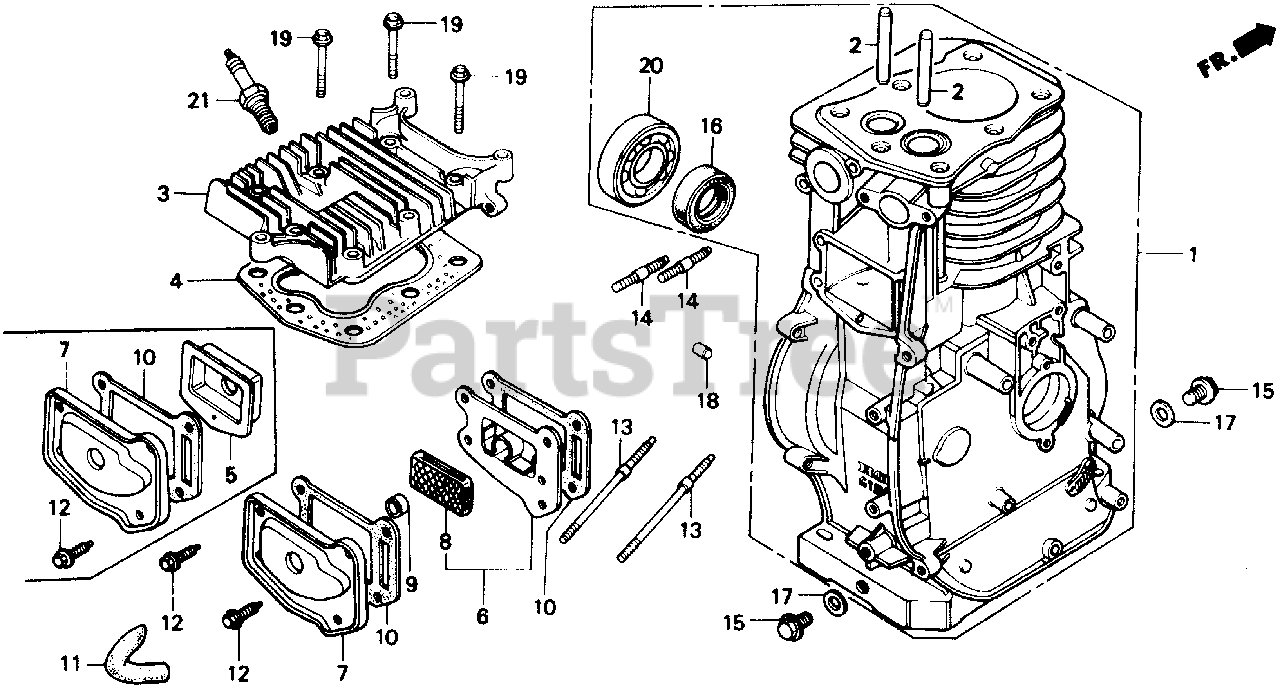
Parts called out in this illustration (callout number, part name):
1	CYLINDER ASSY.
2	GUIDE, VALVE (OS)
3	CYLINDER HEAD
4	GASKET, CYLINDER HEAD
5	CASE, BREATHER
6	CASE, BREATHER
7	COVER, TAPPET ROOM
8	FILTER, BREATHER
9	SEAL, BREATHER
10	GASKET, TAPPET COVER
11	TUBE, BREATHER
12	BOLT, FLANGE (6X12) (CT200)
13	BOLT, STUD (6X89)
14	BOLT, STUD (8X35)
15	BOLT, DRAIN PLUG
16	OIL SEAL (25X41X6)
17	WASHER, DRAIN PLUG (12MM)
18	PIN A, DOWEL (8X14)
19	BOLT, FLANGE (8X45)
20	BEARING, RADIAL BALL (6205)
21	SPARK PLUG (BR-4HS) (NGK)
21	SPARK PLUG (W14FR-U) (DENSO) Use up to Engine SN 1909578.
21	SPARK PLUG (BPR-4HS-10) (NGK)
21	SPARK PLUG (BPR4HS-10) (NGK)
21	SPARK PLUG (W14FPR-UL10) Use from Engine SN 1909579.
